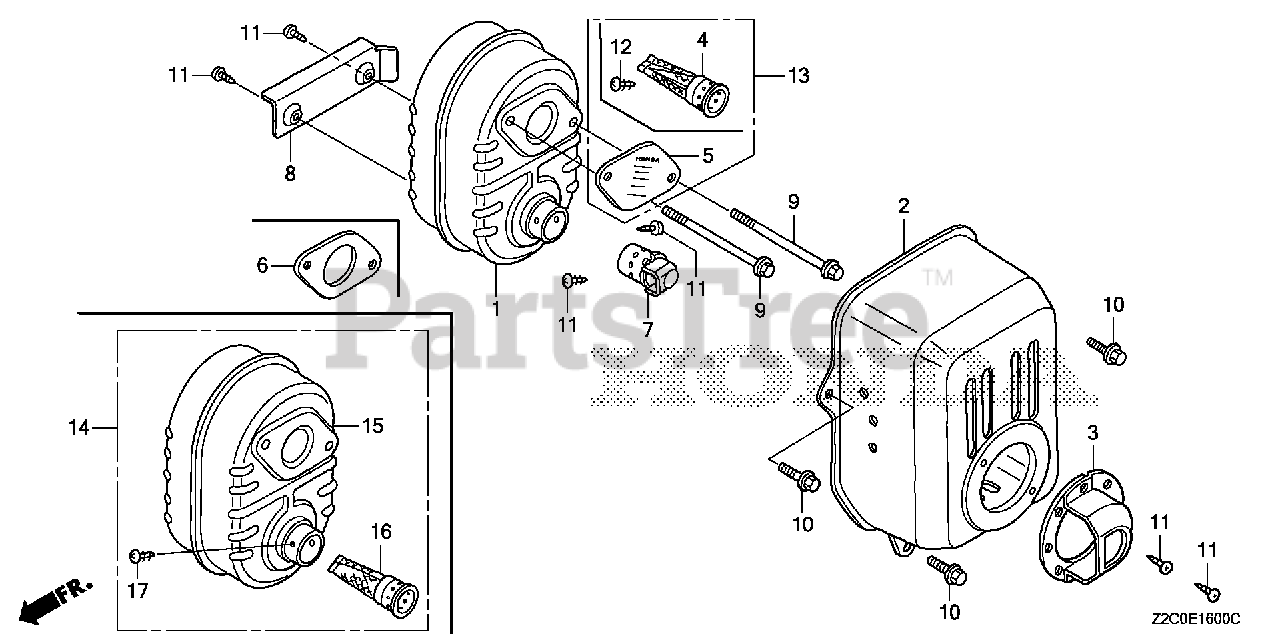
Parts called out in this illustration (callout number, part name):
2	PROTECTOR, MUFFLER
4	ARRESTER, SPARK (TO 1207644)
5	PLATE, ARRESTER NUMBER (TO INSTALL OPTIONAL SPARK ARRESTER)
6	GASKET, MUFFLER
9	BOLT, FLANGE (6X79) (CT200)
10	BOLT, FLANGE (6X12) (CT200)
12	SCREW, TAPPING (4X6) (TO INSTALL OPTIONAL SPARK ARRESTER)
13	ARRESTER KIT, SPARK
14	MUFFLER ASSY. (ARRESTER)
15	MUFFLER
16	ARRESTER, SPARK
17	SCREW, TAPPING (4X6) (TO INSTALL OPTIONAL SPARK ARRESTER)
